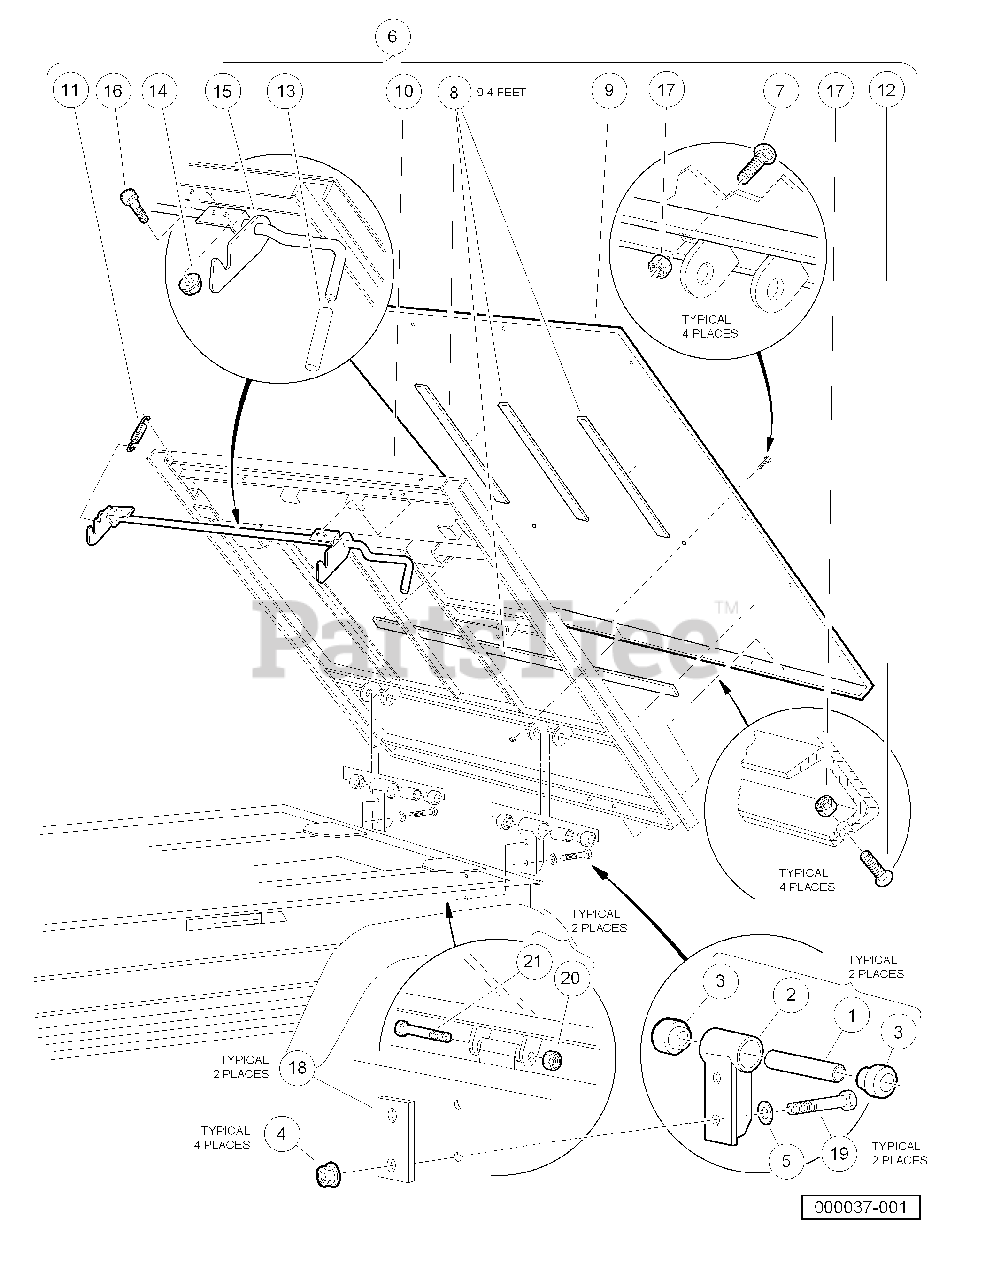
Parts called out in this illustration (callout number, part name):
1	Bushing, Steel
3	Bushing, Urethane
4	Locknut, 3/8-16 Flanged Dimple
5	Washer, 3/8 Type B Hard Flat
6	Tilt Bed Assembly
7	Bolt, Carriage, 5/16-18 X 1.00
8	Tape, Vinyl Foam 1/8" x 3/4"
9	Plate, Floor Bed
10	Frame Assembly
11	Extension, Spring Latch
12	Screw, 5/16-18 X 0.88 Torx Truss-Head
13	Grip, Tilt Latch Hand
14	Locknut, 1/4-20 Hex Whiz
15	Ltch Weld Asm Tlt Bd
16	Screw, 1/4-20 X 0.625 Hex-Head Cap
17	Locknut, 5/16-18 Nylon Insert
18	Plate, Back
19	Bolt, 3/8-16 X 3.00 Hex Head
20	Locknut, 3/8-16 Hex
21	Screw, 3/8-16 X 3.375 Hex Cap
